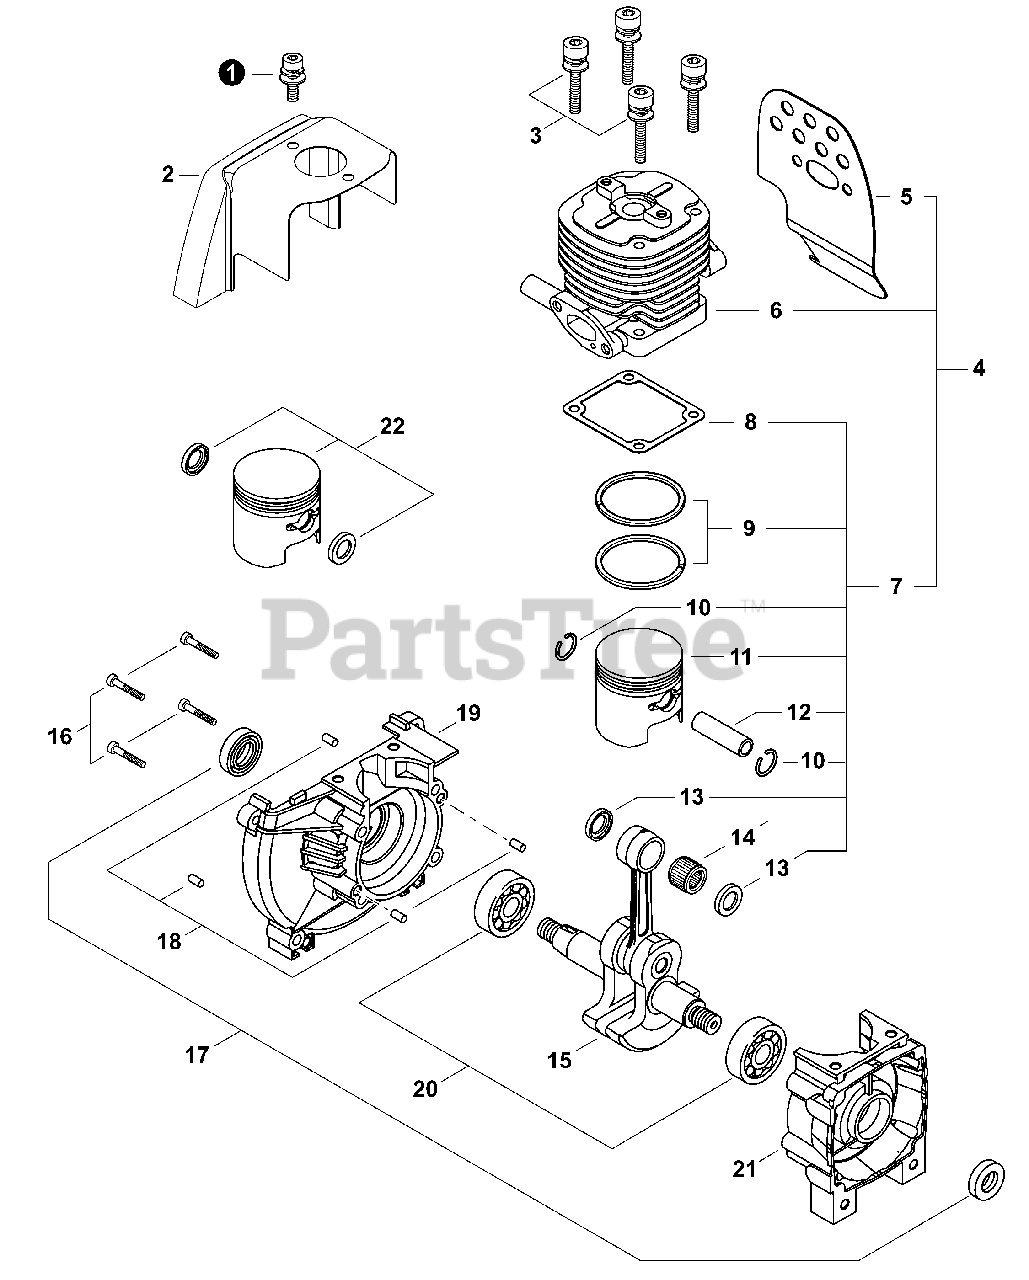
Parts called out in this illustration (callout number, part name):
1	BOLT M5×18
2	STAY, ENGINE COVER
3	COVER, ENGINE
4	BOLT M5×25
5	REBUILD KIT - ENGINE
6	HEAT SHIELD, EXHAUST
7	CYLINDER
8	PISTON KIT
9	GASKET, CYLINDER
10	RING, PISTON
11	RING, SNAP
12	PISTON
13	PIN, PISTON
14	WASHER, THRUST 11
15	BEARING, NEEDLE 11
16	BOLT 5×30
17	CRANKCASE ASSY, M
18	SEAL, OIL 16
19	PIN, LOCATING 5×10
20	CRANKCASE M
21	BEARING, BALL 6202 C3
22	CRANKSHAFT ASSY
23	CRANKCASE ASSY, S
24	BEARING, BALL 6202 C3
25	CRANKCASE S
26	SEAL, OIL 16
27	PISTON SET
